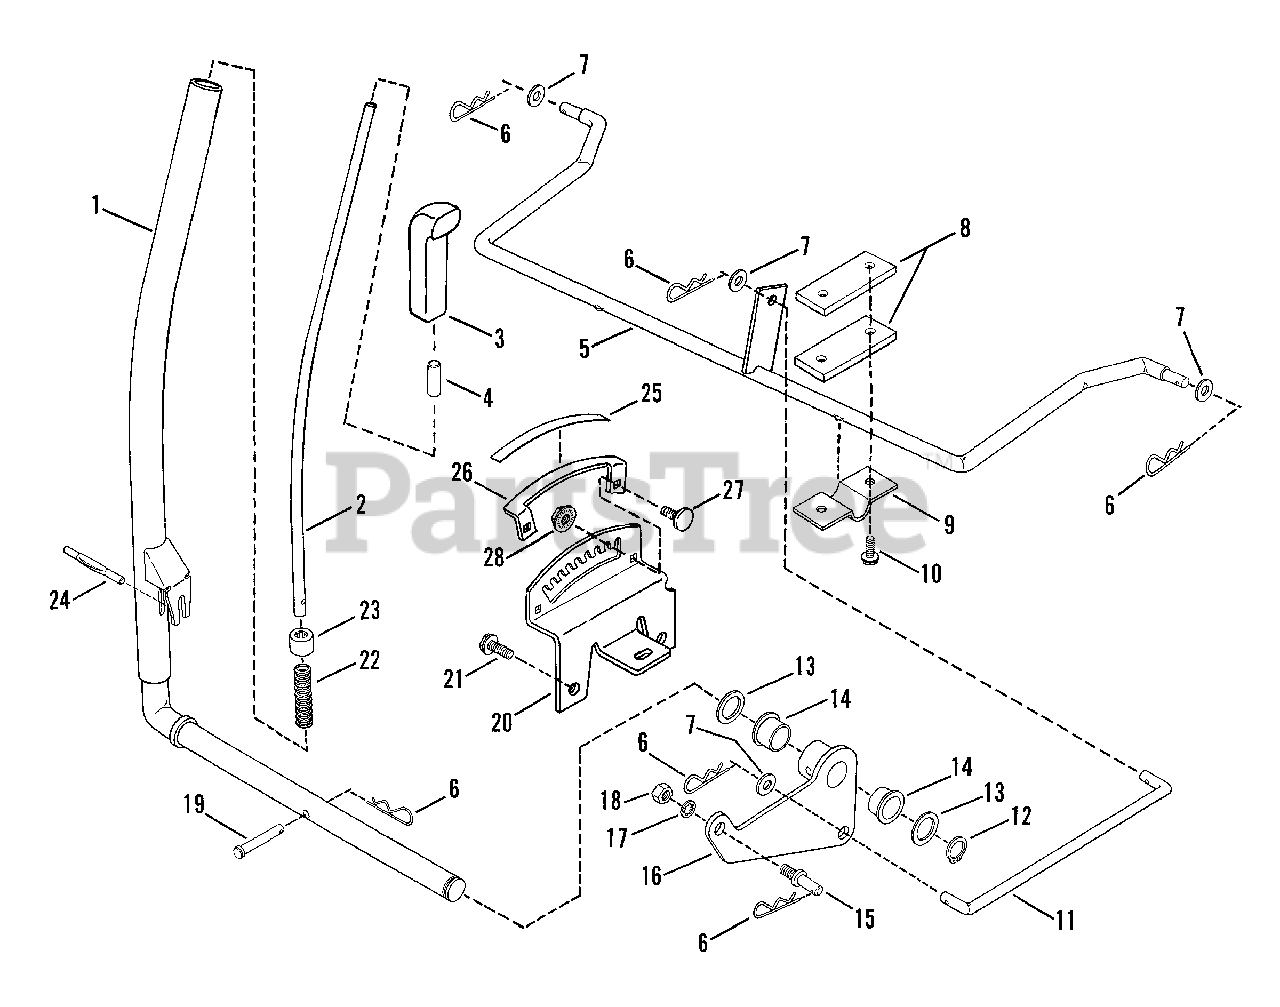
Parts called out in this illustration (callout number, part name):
1	ARM, Implement Lift Lever
2	ROD, Lift Lever
3	GRIP, Lift Lever
4	CAP, Lift Release
5	ARM, Rear Lift
6	PIN, Hair, 3/32 x 1-1/2"
7	WASHER, 3/8 SAE Flat
9	BRACKET, Arm
10	SCREW, 5/16-18 x 1" H.W.H.S.T.
11	LIFT-ROD
12	RING, Retaining
13	WASHER, Lift Lever
14	BEARING, Lift Lever
15	STUD
16	PIVOT ASSM'Y., Lift Lever
17	WASHER, 3/8 Int. Tooth Lock
18	NUT, 3/8-24 Hex
19	PIN, Clevis, 5/16 x 1-11/16"
20	QUADRANT, Lift Lever
21	SCREW, 5/16-18 x 5/8" Self Tapping
22	SPRING, Lift Lever
23	PLUG, Lift Lever
24	GROOVE-PIN, 3/16 x 2"
25	DECAL, Cut Height
26	INDICATOR, Cut Height
27	BOLT, 1/4-20 x 5/8" Flt. Hd. Carr.
28	NUT, 1/4-20 Hex Fig. Lock
